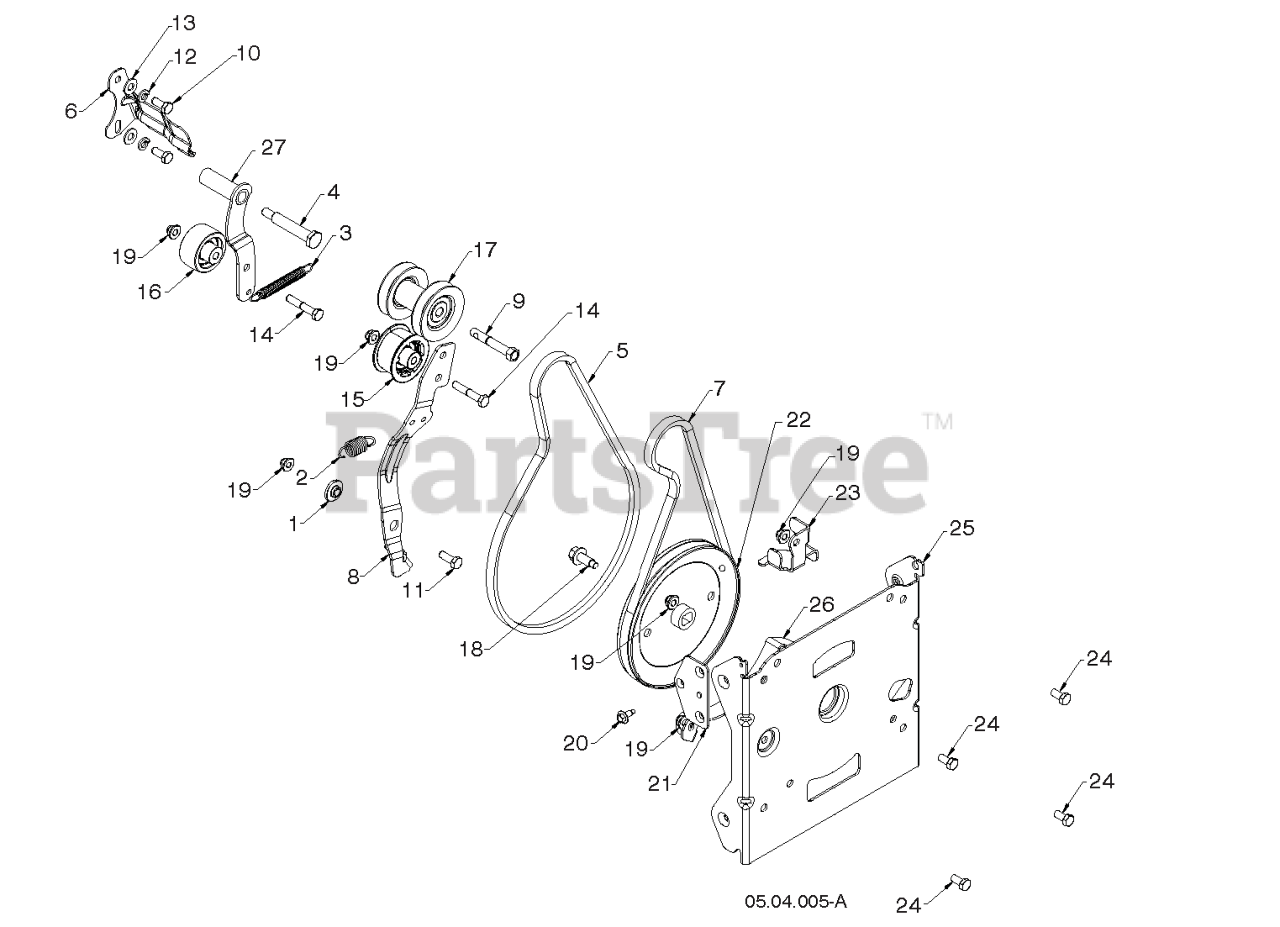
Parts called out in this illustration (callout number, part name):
1	BUSHING.BRAKE.ARM
2	SPRING RETURN, IDLER ARM, IMPE
3	SPRING RETURN IDLER ARM
4	BOLT 5/16-24X2.25 HEX HEAD SHO
5	BELT.HIGH.CRANK.4LX41.RAW.EDGE
6	BELT KEEPER BRACKET
7	HIGH CRANK IMPELLER BELT
8	ARM.IDLER.AUTO-PH.676
9	BOLT.ENGINE.PULLEY
10	SCREW 5/16-24 X .75 GR5
11	BOLT
12	WASHER.LOCK.HVY.HLCL.SPR.5/16
13	WASHER M
14	BOLT, HEX 5/16-18X1-3/4
15	PULLEY,IDLER,2.00 W SPA
16	PULLEY.IDLER.FLANG.2.O/SPACER
17	PULLEY.ASM.IMPELLER/DRIVE
18	SCREW FLANGE HEAD CAP WITH DOG
19	NUTNYLOK.FLRANGE.5/16-18
20	HEX.WASHER.HEAD 1/4-20 X .65
21	BRACKET NUT BLACK ZINC PLATE
22	PULLEY IMPELLER DD 4L
23	GUIDE.LOWER.AUGER.BELT.479
24	BOLT, HEX HEAD 5/16-18
25	BRACKET.AUG.HOUSING.INTER.BLAC
26	BRACKET.BELT.KEEPER.LOWER.BLAC
27	ARM IDLER DRIVE WELDMENT_HOT
